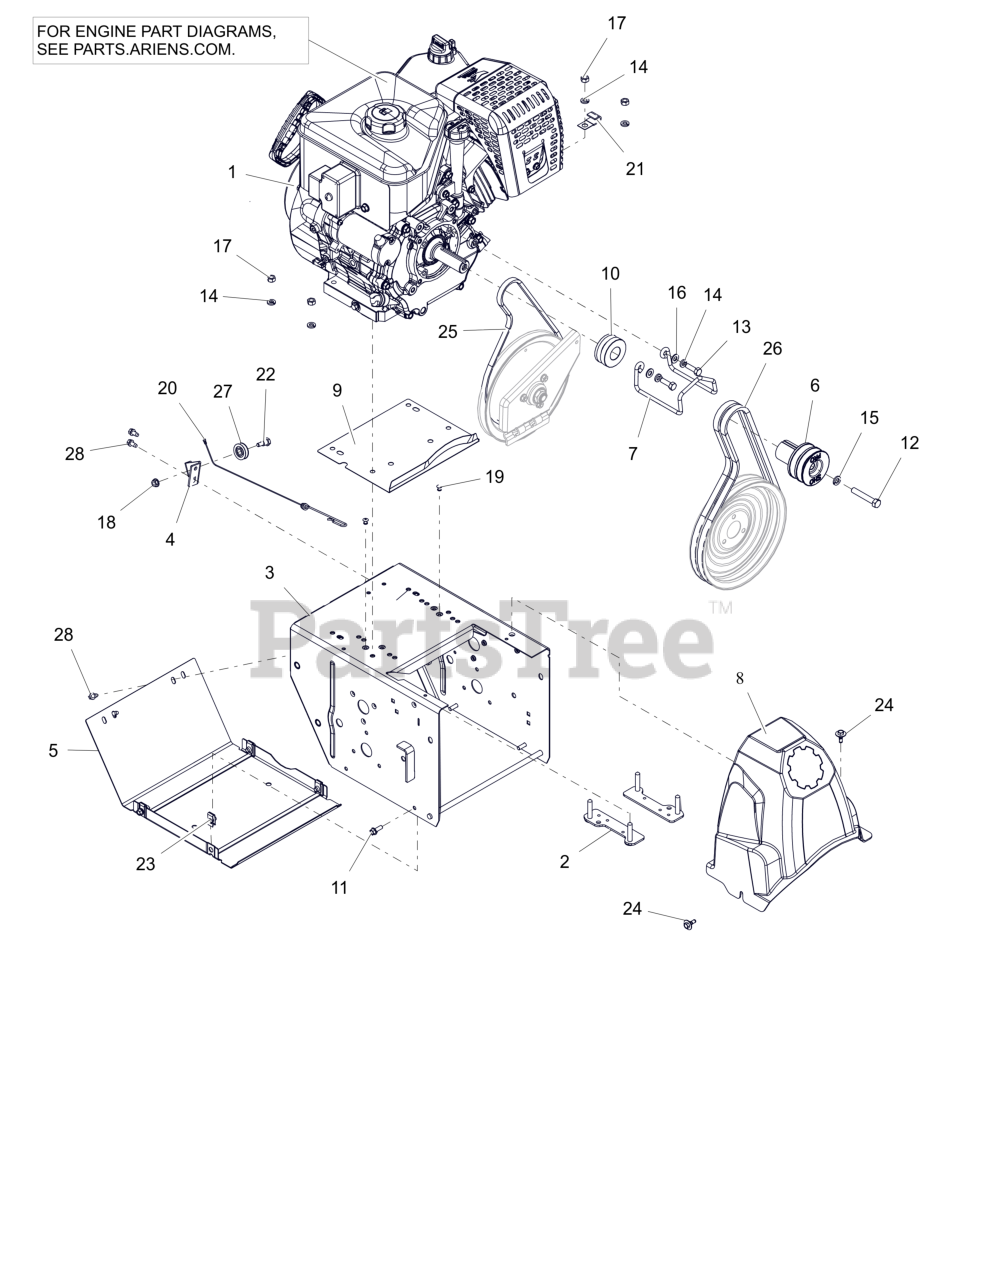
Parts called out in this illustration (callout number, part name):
1	ENGINE, AX414 GEN3 120V/60W
2	STRAP, BOLT-LARGE
3	FRAME, MAIN - 14GA DELUXE (ORANGE)
4	BRACKET, CABLE PULLEY
5	COVER, BOTTOM
6	SHEAVE,ATTACHMENT-SHO 2 GRV
7	FINGER, BELT
8	COVER, BELT
9	BAFFLE, WATER - LARGE BLOCK
10	SHEAVE, TRACTION (KEYLESS)
11	BLT, HWH .25-20X.75 G5 ZCC
12	BLT, HEX .38-24X2.25 G5 ZCC
13	BLT, HEX 0.3125-24X1 G5 ZCC
14	WSHR, LK-HVY .312X.097 ZCC
15	WSHR,LK-REG .375X.094 ZCC
16	WSHR,FLT .344X.688X.065 ZCC
17	NUT, HEX .312-18 ZCC
18	NUT-LK-TOP-FLG .250-20 GF ZCC
19	RVT, POP .1875 ZCC
20	CABLE, LOWER TRACTION,SS & PRO
21	J-CLAMP
22	BOLT, SHLDR -.375 X .375 X .25-20
23	NUT-RTNR .25-20X.56
24	SCR-TAP .25-20X.5 CAPTIVE
25	V-BELT, 3L-WRAPPED
26	V-BELT, HA-RAW EDGE (SET)
27	PULLEY, CABLE
28	SCR-TAP .25-20X.50 HWH ZCC
